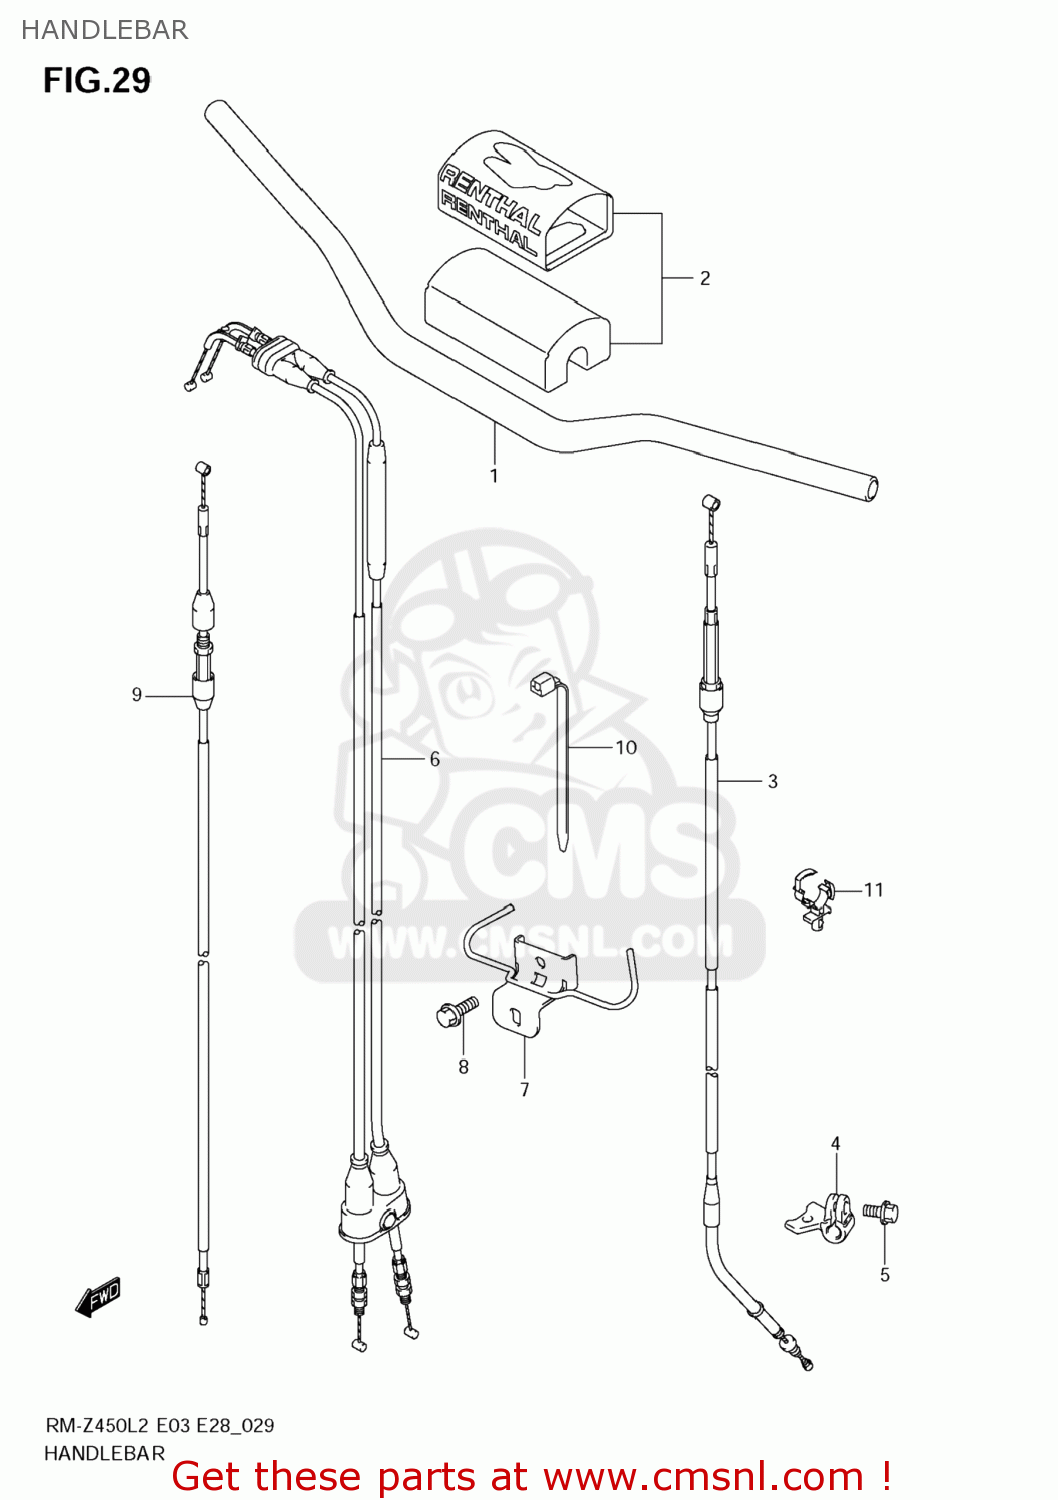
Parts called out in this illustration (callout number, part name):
1	HANDLEBAR
2	PAD SET,HANDLEBAR (NAS)
3	CABLE ASSY,CLUTCH
4	BRACKET,CLUTCH CABLE
5	BOLT
6	CABLE SET,THROTTLE
7	BRACKET,COUPLER
8	BOLT
9	CABLE ASSY,HOT STARTER
10	CLAMP(L:95)
11	CLAMP
